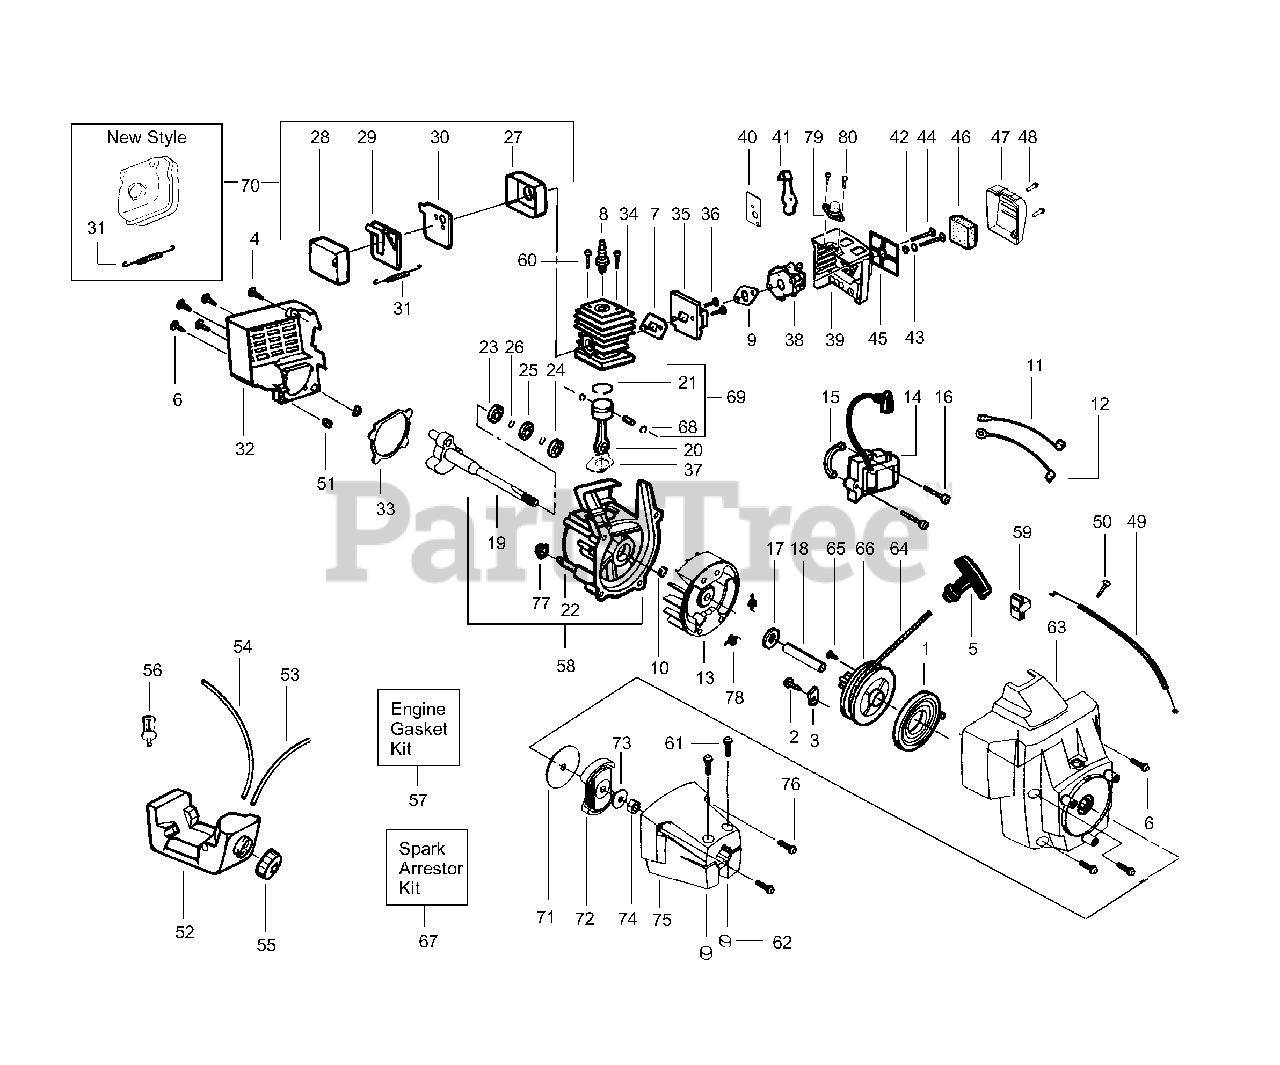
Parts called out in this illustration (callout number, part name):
1	Starter Spring
3	Retainer
5	Starter Handle
6	Screw
7	Cylinder Gasket
8	Spark Plug
10	Retainer
11	Lead Wire
12	Ground Wire
13	Flywheel Ass'y.
14	Ignition Module
19	Crankshaft Ass'y.
20	Connecting Rod Ass'y.
21	Piston Ring
22	Crankcase Ass'y.
23	Inner Bearing
24	Outer Bearing
25	C'case Seal
26	Retaining Ring
27	Muffler Body
28	Muffler Cover
29	Muffler Baffle-Exit
30	Muffler Baffle-First
31	Muffler Spring Old Style
31	Muffler Spring New Style
34	Cylinder Kit
35	Carb. Adaptor Kit
38	Carburetor Ass'y.
40	Choke Plate
41	Choke Shutter
42	Wave Washer
43	Choke Spacer
45	Filter Plate
46	Air Filter Foam
47	Air Filter Cover
49	Throttle Cable Ass'y.
51	Isolator-Shroud
52	Fuel Tank Ass'y.
53	Fuel Line-Primer/Tank
54	Fuel Line-Carb/Tank
55	Fuel Cap Ass'y.
56	Fuel Pickup Ass'y.
57	Engine Gasket Kit
58	C'case & C'shaft Assy.
59	Switch Kit
63	Fan Housing
64	Rope Kit
66	Starter Pulley
67	Spark Arrestor Kit Old Style
67	Spark Arrestor Kit New Style
68	Piston Pin Retainer
69	Piston Kit
70	Muffler Kit Old Style
70	Muffler Kit New Style
72	Clutch Ass'y.
75	Clutch Hsg.
77	Isolator-Crankcase
78	Starter Spring
79	Bulb Ass'y.
